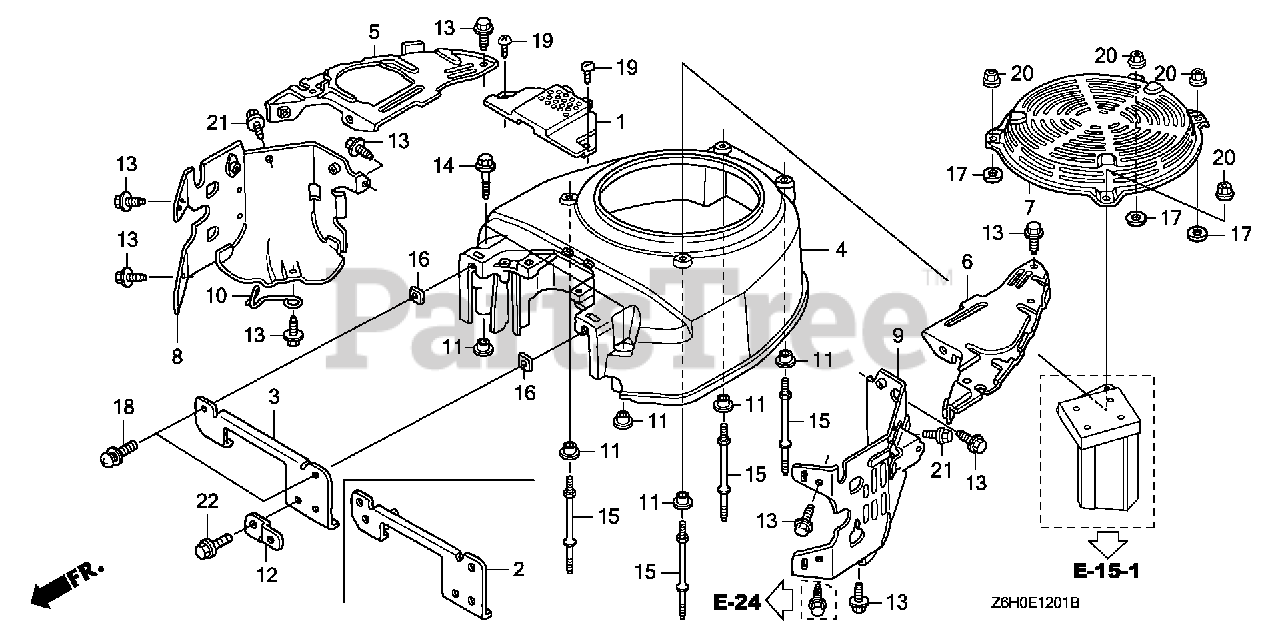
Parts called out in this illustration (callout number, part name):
1	COVER, FUEL PUMP
2	COVER, FUEL PUMP
4	COVER, FAN *R280* (RECOIL STARTER) (POWER RED)
5	PLATE, SIDE
6	PLATE, SIDE
7	PROTECTOR, FAN COVER *R280* (POWER RED)
10	CLAMP, IGNITION TUBE
11	COLLAR B, TAILLIGHT
13	BOLT, FLANGE (6X12) (CT200)
14	BOLT, FLANGE (6X23) (CT200)
15	BOLT, STUD (6X71)
16	NUT, SQUARE (5MM)
18	SCREW-WASHER (5X12)
19	SCREW, TAPPING (5X20)
20	NUT, FLANGE (6MM)
21	BOLT, FLANGE (6X8)
